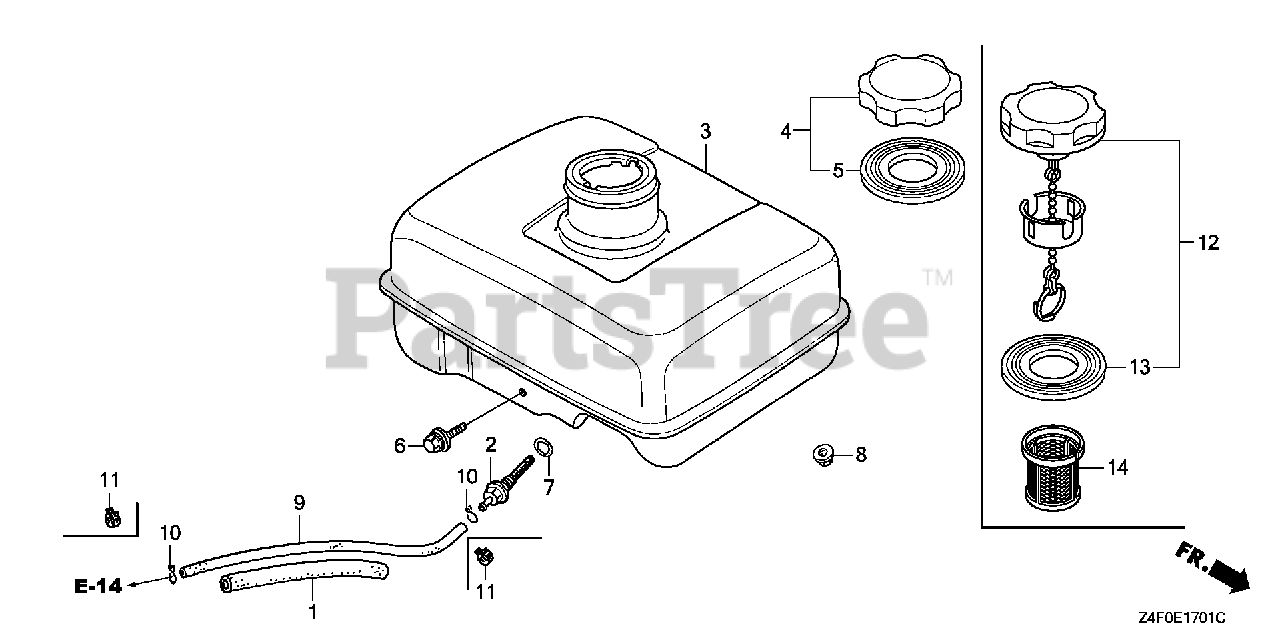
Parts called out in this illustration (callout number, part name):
1	RUBBER, SUPPORTER (107MM)
2	JOINT, FUEL TANK
3	TANK, FUEL *NH105* (MAT BLACK)
4	CAP, FUEL FILLER (CHROME PLATED)
5	GASKET, FUEL FILLER CAP (39X62X3) (TOUYOUSYA)
6	BOLT, FLANGE (6X29)
7	O-RING (13.5X1.5) (ARAI)
7	O-RING (14MM) (NOK)
8	NUT, FLANGE (6MM)
9	TUBE, FUEL (4.5X140) (FKM)
9	BULK HOSE, FUEL (4.5X3000) (4.5X140)
10	CLIP, TUBE (B8)
11	CLAMP, TUBE (D8)
12	CAP, FUEL FILLER (CHROME PLATED)
12	CAP, FUEL FILLER
13	GASKET, FUEL FILLER CAP (39X62X3) (RADICON)
